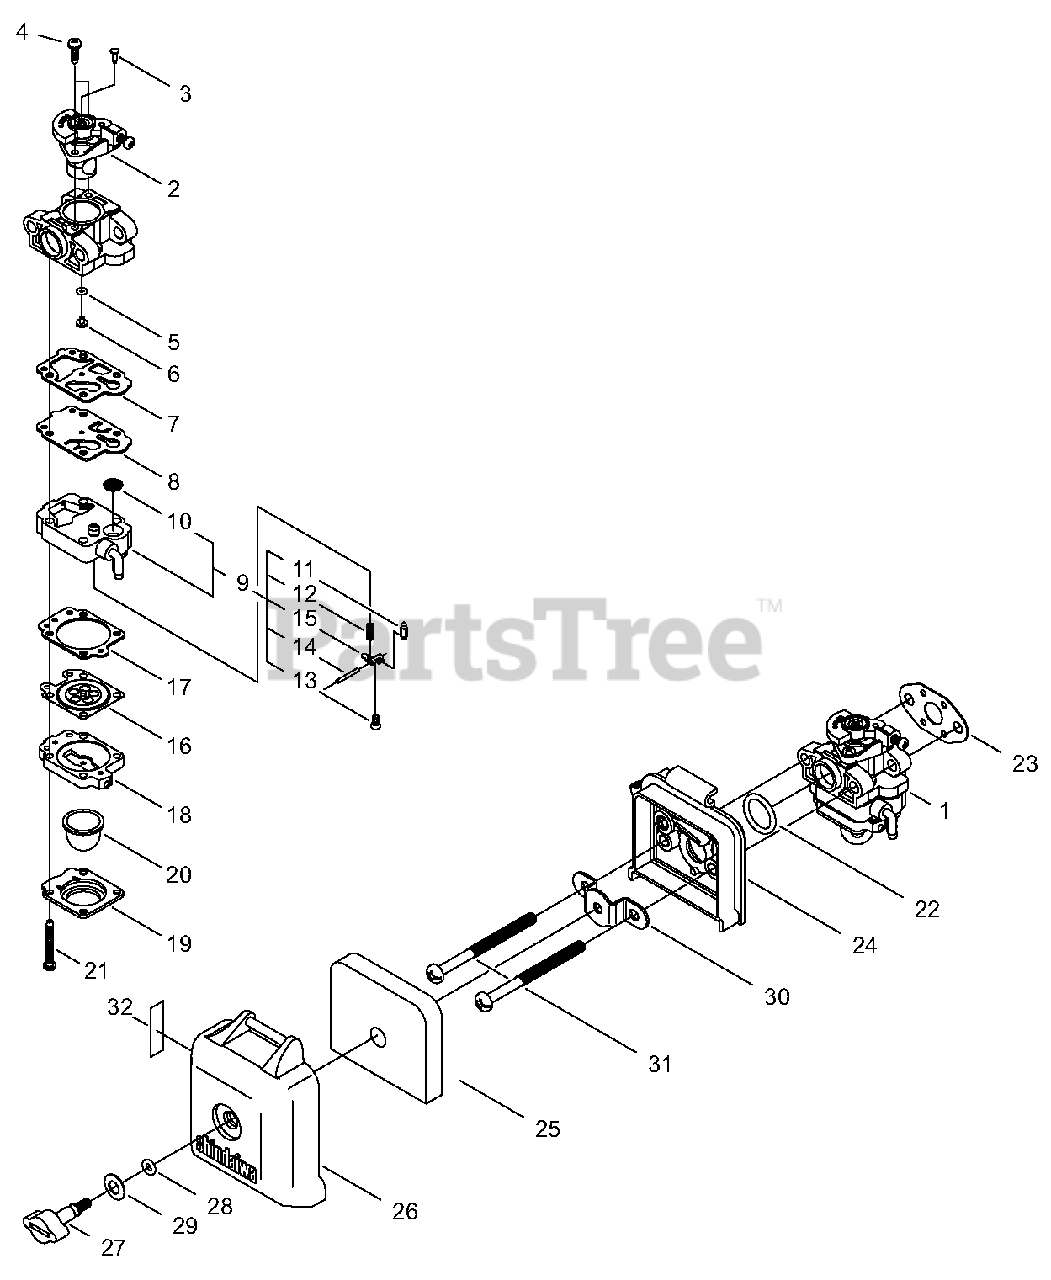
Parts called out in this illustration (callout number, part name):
1	CARBURETOR
2	VALVE, THROTTLE
3	PLUG, WELCH
4	SCREW
5	O-RING
6	JET, MAIN - 40
7	GASKET, PUMP
8	DIAPHRAGM, PUMP
9	PUMP BODY ASSY
10	STRAINER
11	VALVE, INLET NEEDLE
12	SPRING, METERING LEVER
13	SCREW, METERING LEVER PIN
14	PIN, METERING LEVER
15	LEVER, METERING
16	DIAPHRAGM, METERING
17	GASKET, METERING
18	PURGE BASE ASSY
19	RETAINER, PURGE BULB
20	BULB, PURGE
21	SCREW, PUMP COVER
22	O-RING - 15
23	GASKET, INTAKE
24	CASE, AIR FILTER
25	FILTER, AIR - FOAM
26	COVER, AIR FILTER
27	THUMBSCREW
28	O-RING
29	WASHER - CONICAL
30	PLATE, PREVENT
31	SCREW - 5X60
32	LABEL - CHOKE
